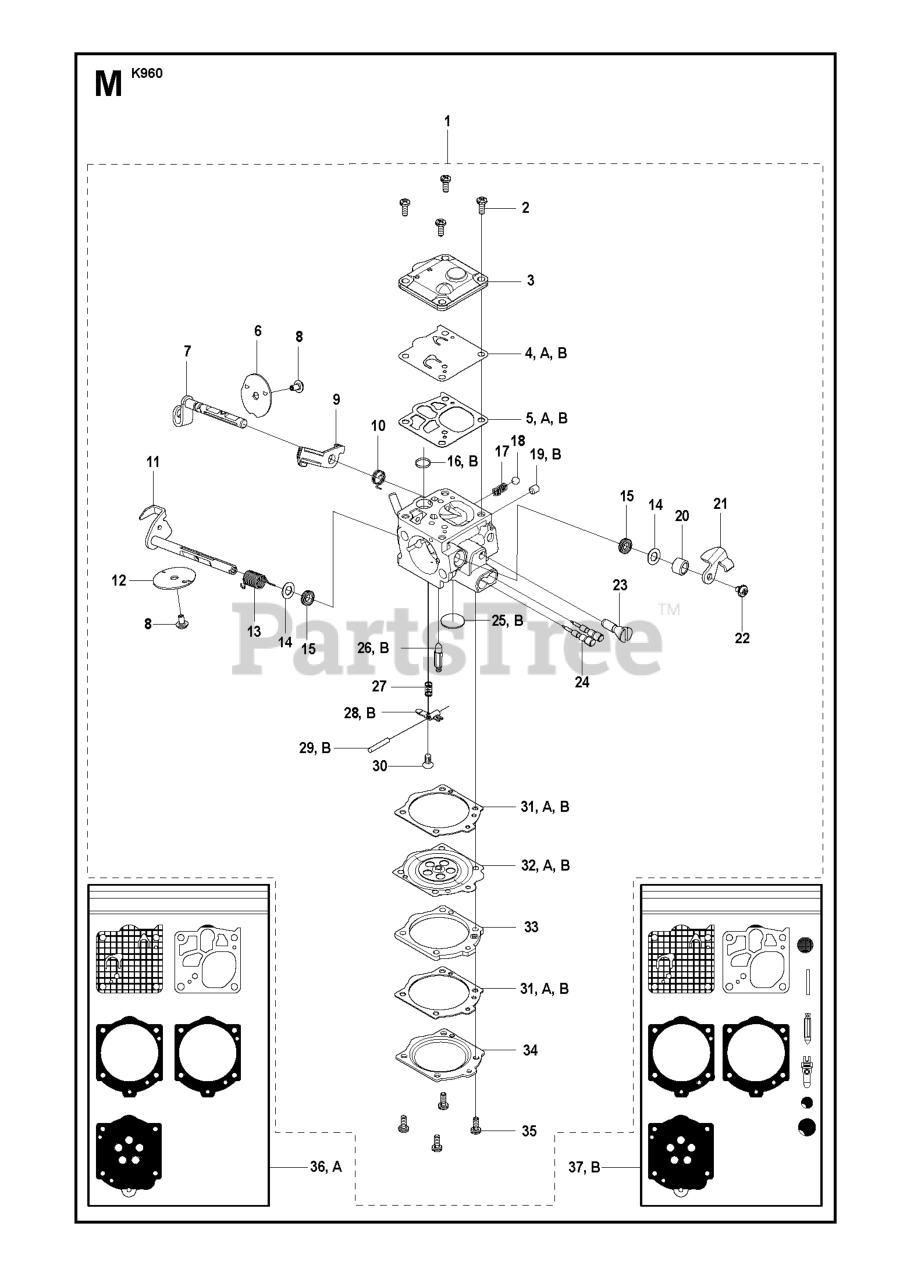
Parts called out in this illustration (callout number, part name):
1	CARBURETOR ASSY RWJ-3
2	SCREW W/ WASHER
3	COVER
4	DIAPHRAM PUMP
5	GASKET
7	SHAFT CHOKE ASSY
10	SPRING FAST IDLE RETURN
11	SHAFT, THROTTLE ASSY
16	FUEL INLET SCREEN
19	PLUG
25	WELCH PLUG
26	VALVE INLET NEEDLE
27	SPRING-METER.LEVER
28	LEVER
29	PIN
31	GASKET
32	DIAPHRAM PUMP
36	GASKET KIT
37	REPAIR KIT
